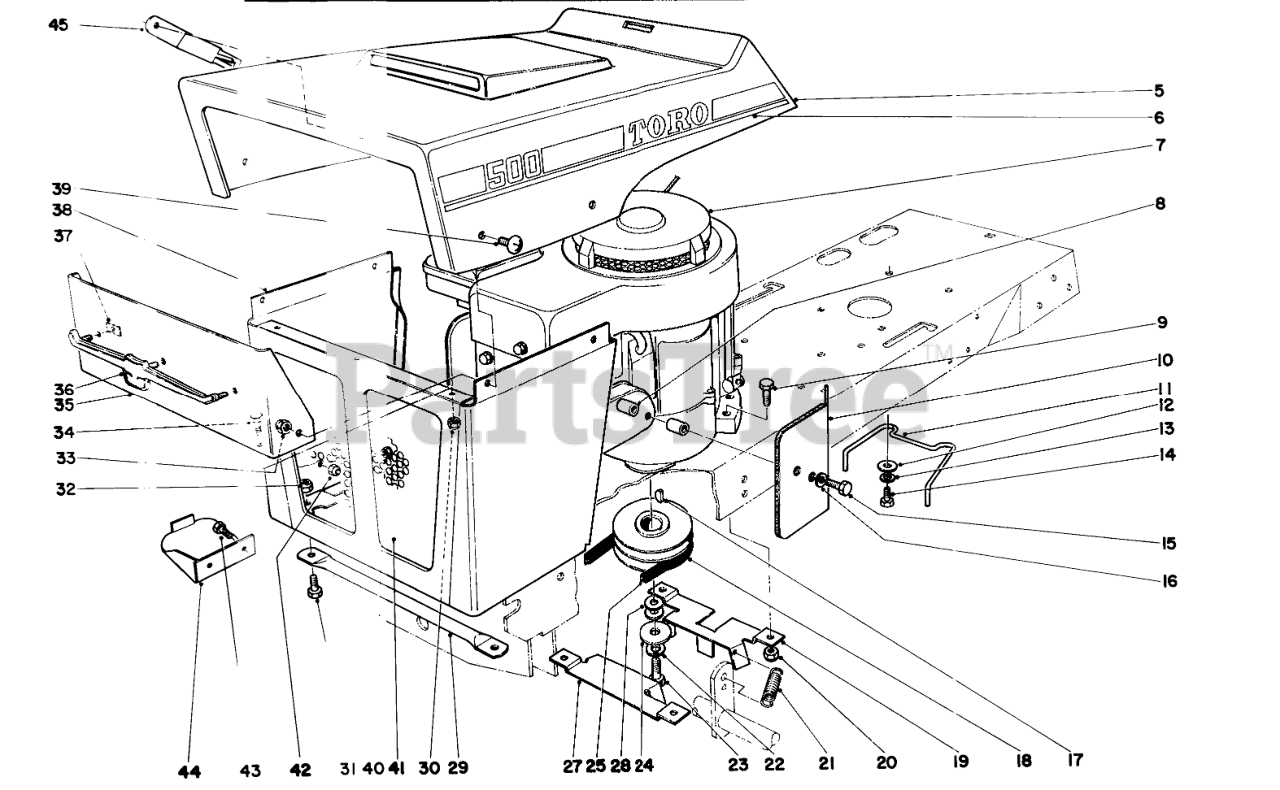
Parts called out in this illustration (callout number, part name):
6	Decal Hood L.H. (Recoil)
7	Engine
8	Spacer
9	SCREW-HH
10	Baffle Assembly
11	Belt Retainer
12	WASHER-PLAIN
13	WASHER-LOCK/SP
14	SCREW-HH
15	SCREW-HH
16	WASHER-LOCK
17	KEY-WOODRUFF
18	Engine Pulley
19	Belt Guide
20	Nut
21	Spring
22	WASHER-LOCK
23	SCREW-HH
24	Washer
25	ENGINE BELT
27	Belt Guide
28	WASHER-FLAT
29	Rod Grille Mount
31	SCREW-HH
33	Nut
34	SCREW-HH
35	Grille Panel
36	Bullshead
37	Tinnerman Nut
38	Grille Assembly (Recoil)
39	Truss Head Screw
40	NUT-LOCK, NI
41	Grille Panel
42	NUT-LOCK, CONE
43	SCREW-HH
44	Trimmer Support
45	Clip Trimmer
